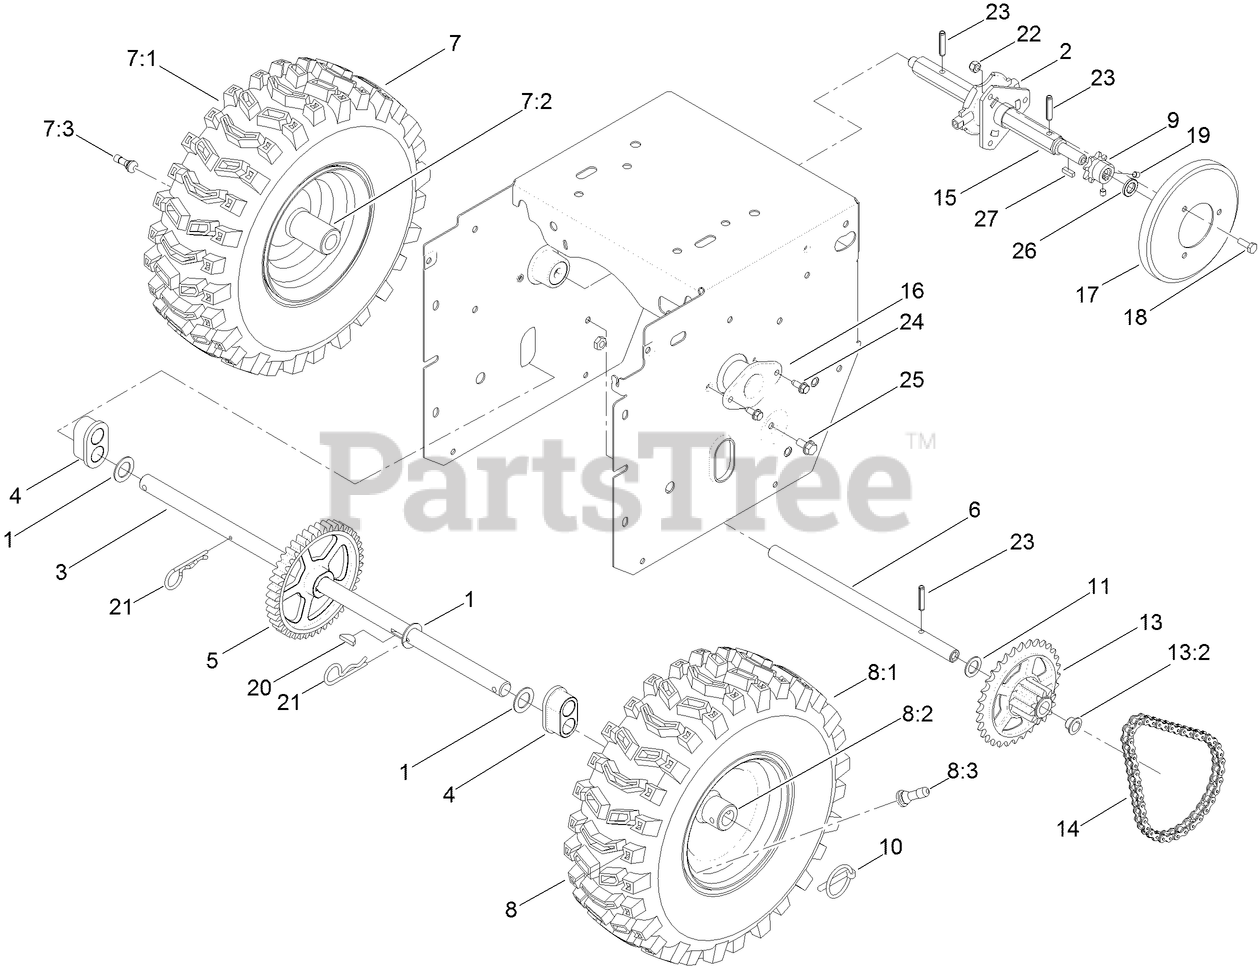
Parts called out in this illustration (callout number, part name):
1	WASHER-THRUST
2	TRUNNION-HEX
3	SHAFT-AXLE
4	BEARING-AXLE
5	GEAR-AXLE, 44 TOOTH
6	SHAFT-INTERMEDIATE
7	Loose Parts Package
7:2	RIM-TIRE
8	Loose Parts Package
8:2	RIM-TIRE
9	SPROCKET-8 TOOTH
10	KLIK PIN ASM
11	WASHER-FLAT
13	SPROCKET ASM
13:2	BUSHING-FLANGE
14	CHAIN-ROLLER
14	LINK-CONNECTING
15	SHAFT-HEX
16	RETAINER-BEARING
17	WHEEL-FRICTION
18	SCREW-HH
19	SCREW-HSH
20	KEY-WOODRUFF
21	PIN-HAIR
22	NUT-LOCK, NI
23	PIN-ROLL, SLOTTED
24	SCREW-HWH
25	SCREW-HWHTF
26	SPACER-BUSHING
27	KEY-SQUARE
